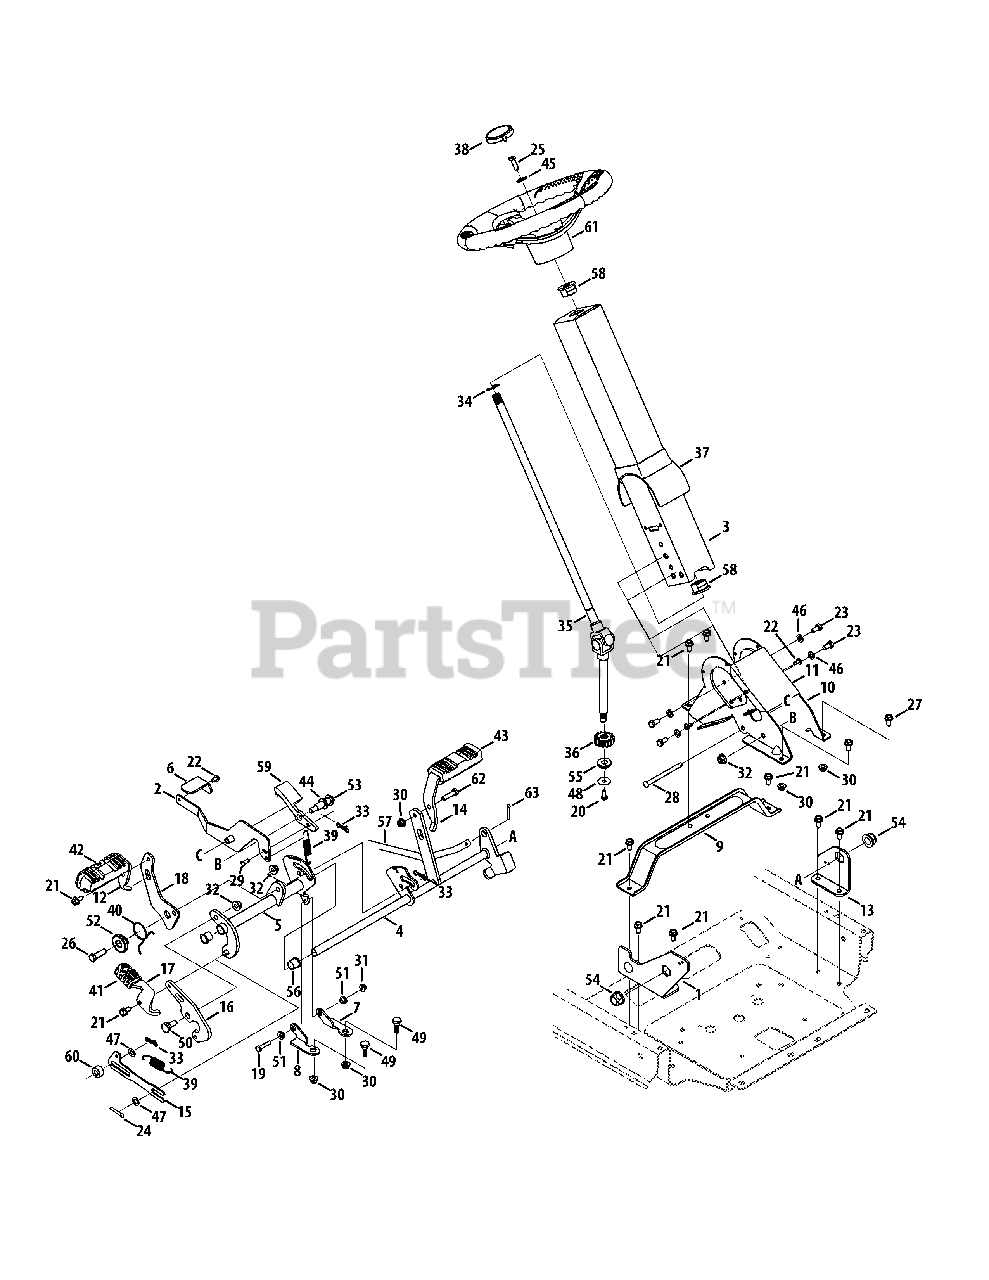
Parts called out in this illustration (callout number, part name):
1	Support Bracket Assembly, RH
2	Brake Pedal Assembly
3	Steering Column Assembly
4	Brake Pedal Assembly
5	Drive Pedal Assembly
6	Tilt Steering Pedal
7	Speed Bracket, LH
8	Speed Bracket, RH
9	Steering Support Bracket
10	Lower Steering Wheel Column
11	Lower Column Cover
12	Drive Pedal
13	Support Bracket, LH
14	Brake Pedal
15	Return to Neutral Link
16	Reverse Pedal Bracket
17	Reverse Pedal
18	Forward pedal Bracket
19	Hex Head Screw, 1/4-20 x 1.25
20	Hex Head Screw, 1/4-20 x .625
21	Hex Washer Screw, 5/16-18 x .750
22	Screw, 1/4-20 x .5
23	Hex Screw, 5/16-18 x .625
24	Cotter Pin, .125 x .75
25	Hex Screw, 5/16-24 x.875
26	Hex Screw, 3/8-16 x 1.25
27	Hex Screw, 5/16-18 x .75
28	Clevis Pin, 5/16 x 4.135
29	Clevis Pin, .224 Dia. x .625
30	Flange Lock Nut, 5/16-18
31	Flange Lock Nut, 1/4-20
32	Flange Lock Nut, 3/8-16
33	Bow-Tie Cotter Pin, 72
34	E-Ring, .750
35	Steering Shaft
36	14-Tooth Spur Gear
37	Column Cover
38	Steering Wheel Cover
39	Extension Spring, .70 OD x 3.035 LG
40	Torsion Spring, 1.00 ID x .22
41	Reverse Pedal Pad
42	Forward Pedal Pad
43	Brake Pedal Pad
44	Flat Washer, .535 x .930 x .090
45	Bell Washer, .340 x .872 x .060
46	Flat Washer, .330 x .630 x .064
47	Thrust Washer, .375 x .700 x .030
48	Flat Washer, .265 x 1.00 x .030
49	Shoulder Screw, 5/16-18 x .437 x .268
50	Shoulder Bolt, 3/8-16 x .500 x .270
51	Shoulder Spacer, .375 x .625 x .20
52	Shoulder Spacer, 1.50 x .38 x .38
53	Shoulder Screw, 3/8-16 x .496 x 1.445
54	Hex Flange Bearing
55	Hex Flange Bearing, 7/16
56	Flange Bearing, .63 ID x .695 OD x .06
57	Front Brake Rod
58	Flange Bearing, .63 ID x 1.50
59	Cruise Latch
60	Spacer, .385 ID x .875 OD x .458
61	Steering Wheel Assembly
62	Hex Cap Screw, 5/16-18 x 1.00
63	Cotter Pin, 5/32 x 1.25
